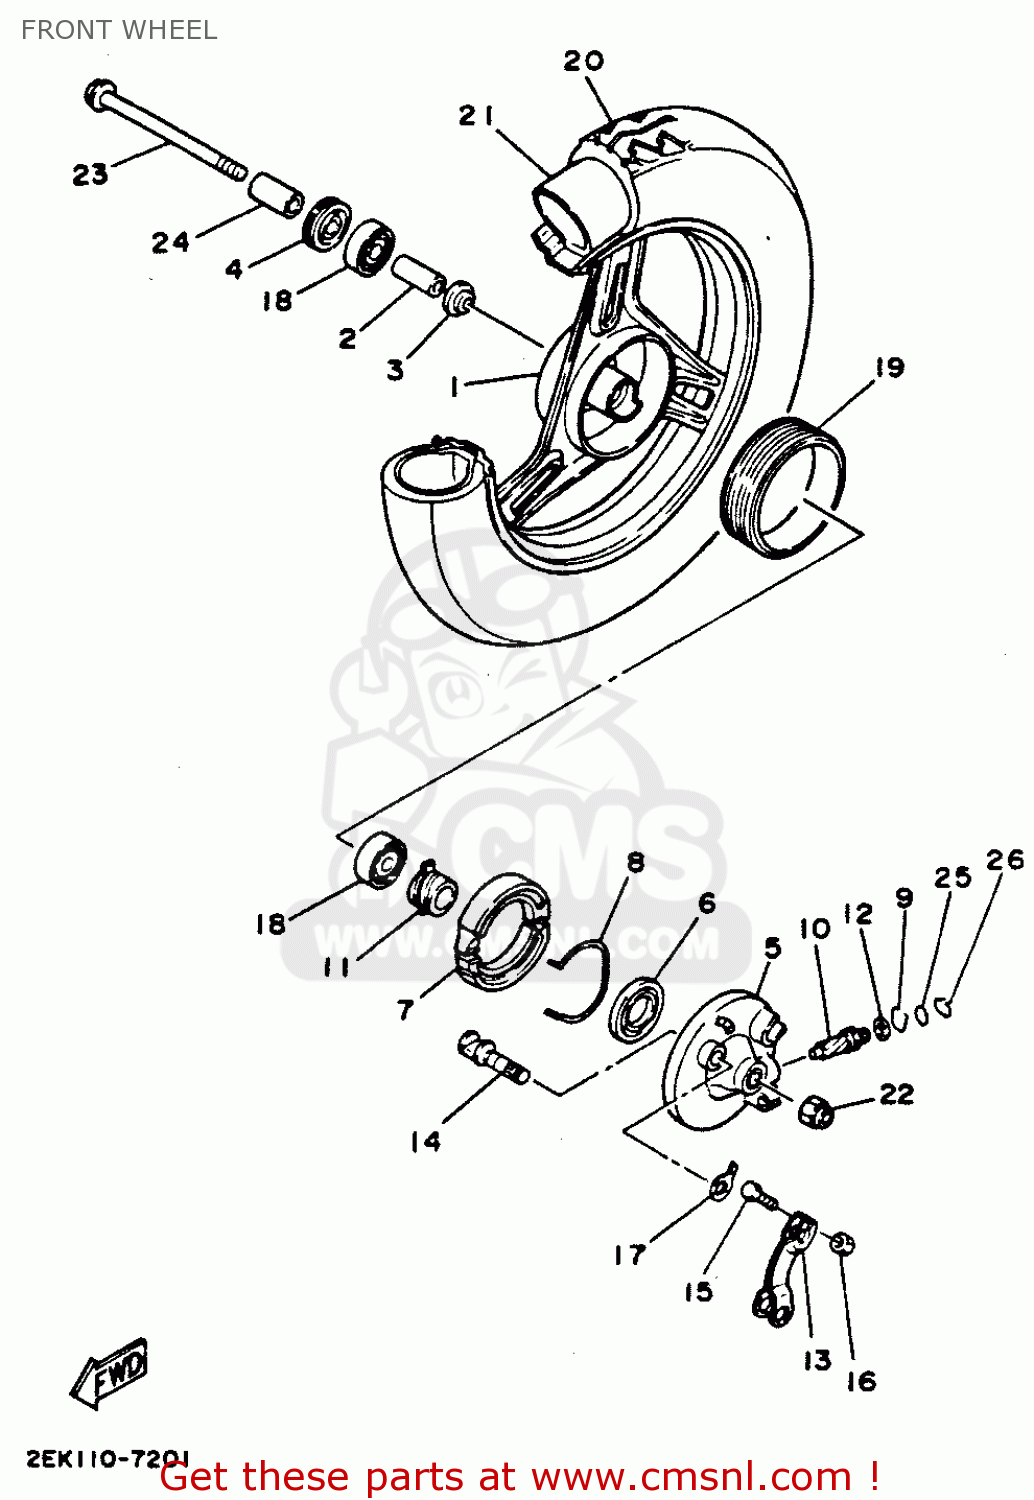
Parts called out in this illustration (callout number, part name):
1	FRONT WHEEL COMP.
2	SPACER (25K)
3	FLANGE, SPACER 2
4	OIL SEAL (2E9)
5	PLATE, BRAKE SHOE
6	OIL SEAL(2JA)
7	BRAKE SHOE SET (NAS)
8	SPRING, SHOE RETURN
9	RING, STOP
10	GEAR, METER
11	GEAR, DRIVE (14T)
12	WASHER,PLATE (2JA)
13	LEVER, CAMSHAFT 1
14	CAMSHAFT
15	BOLT(3AL)
16	NUT HEXAGON(663)
17	INDICATOR
18	BRG,R-B 6200 30MM 32G KY
19	RING 1
20	TIRE (2.50-10)(2EK)
21	TUBE (2.75-10) (27V)
22	NUT, SELF-LOCKING(J17)
23	AXLE, WHEEL
24	COLLAR (2E9)
25	O-RING (611)
26	RING (STOP)
